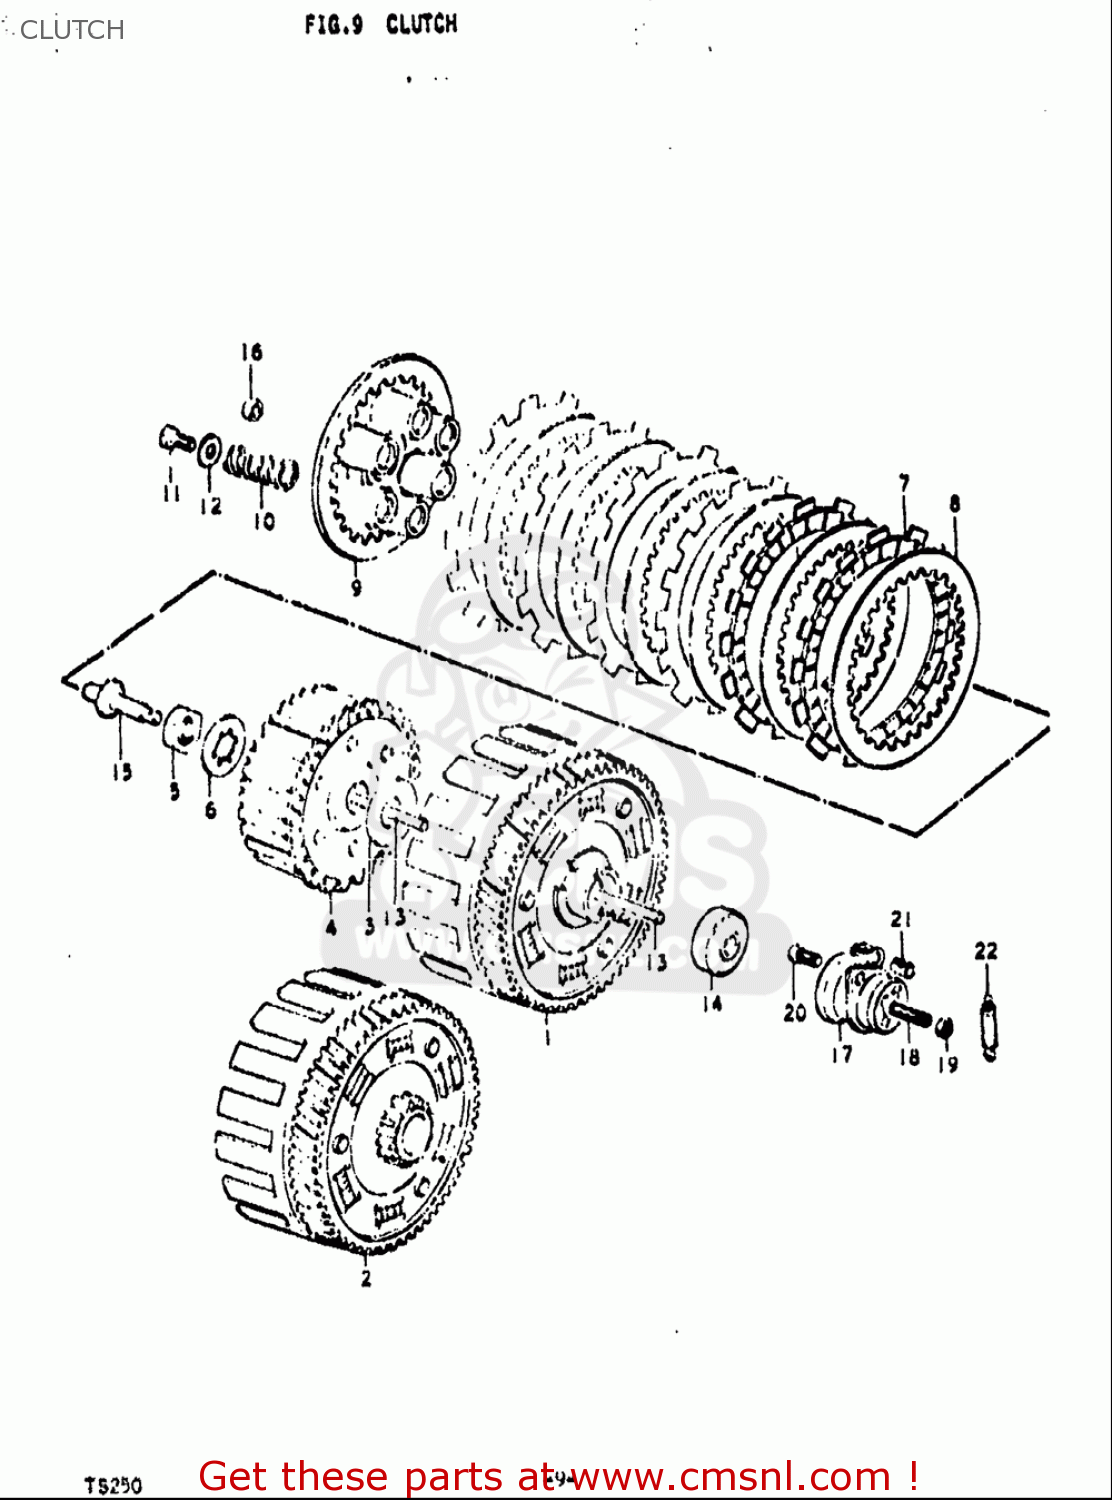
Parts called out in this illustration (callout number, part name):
2	GEAR ASSEMBLY,PRIMARY DRIVE
3	WASHER(20X44X3)
5	NUT
6	WASHER,LOCK
7	PLATE,CLUTCH DRIVE(T:3.5) (NAS)
8	PLATE,CLUTCH DRIVEN(T:2.0) (NAS)
10	SPRING
11	BOLT
12	WASHER(6.5X20X1.6)
13	ROD,CLUTCH PUSH
14	SEAL,OIL (6X30X5)
16	SEAL,OIL (10X17X5)
17	SCREW ASSY,CLUTCH RELEASE
18	SCREW(6X25)
19	NUT
20	SCREW
21	PIECE,RELEASE ARM END
22	SPRING
